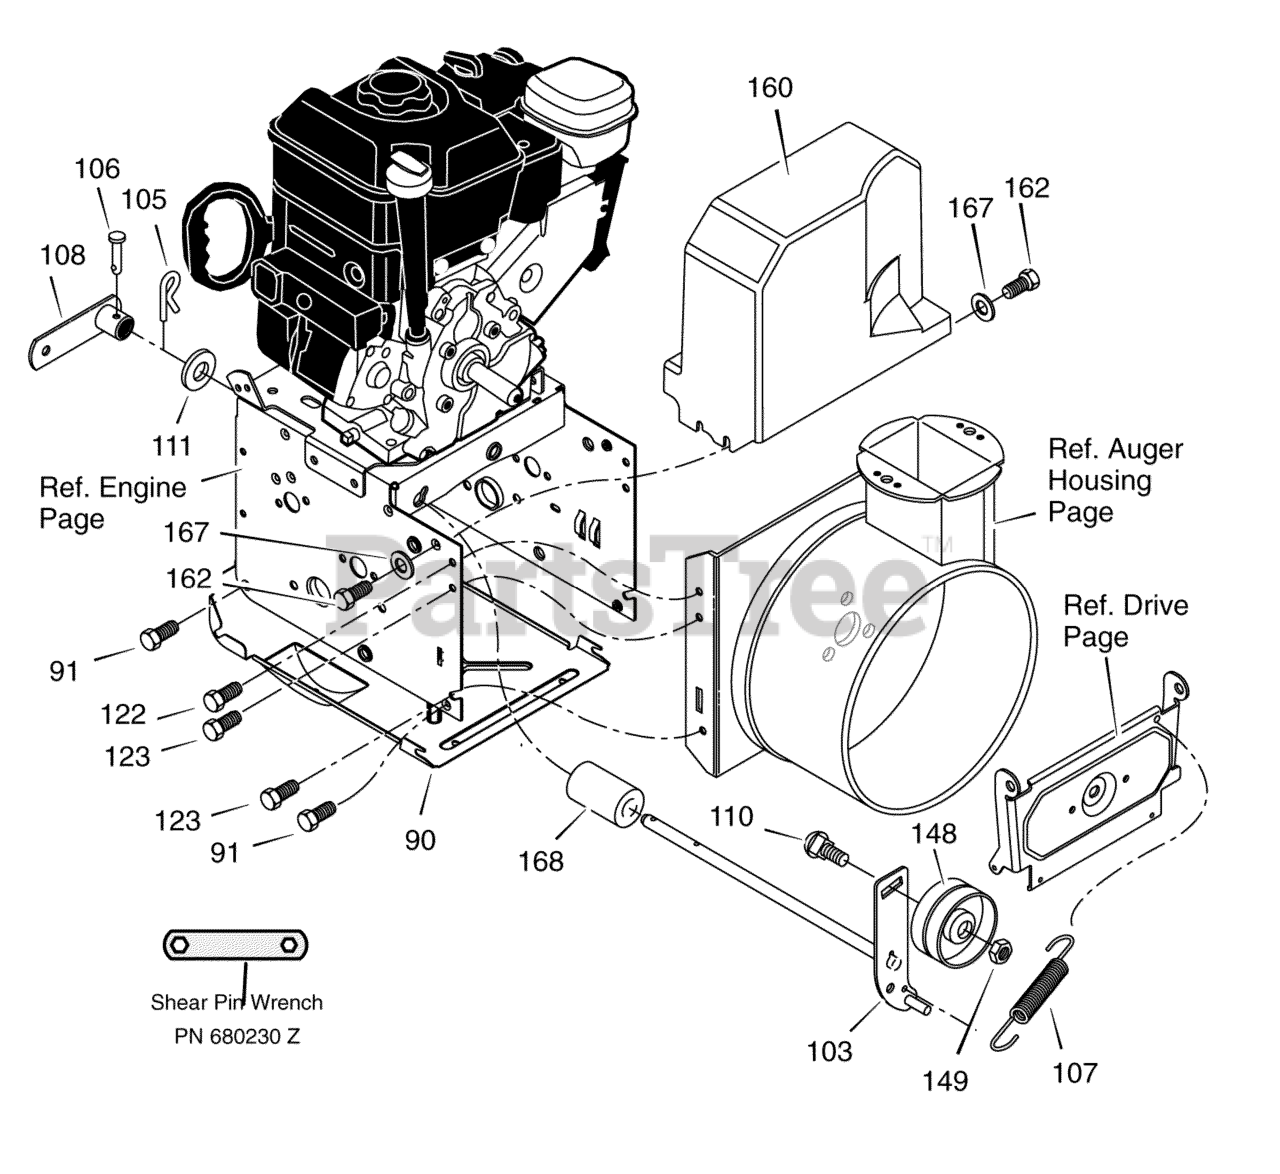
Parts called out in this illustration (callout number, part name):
90	COVER, BOTTOM
91	SCREW
103	IDLER, AUGER
105	PIN, HAIR
106	PIN, CLEVIS
107	SPRING, TENSION
108	SPRING ATTACH
110	BOLT, CARRIAGE
111	WASHER, FLAT
122	SCREW, TAP
123	SCREW, TAP
148	PULLEY, IDLER
149	NUT, JAM 3/8-16
160	COVER, BELT
162	SCREW, TAP
167	WASHER, FLAT
168	SPACER
